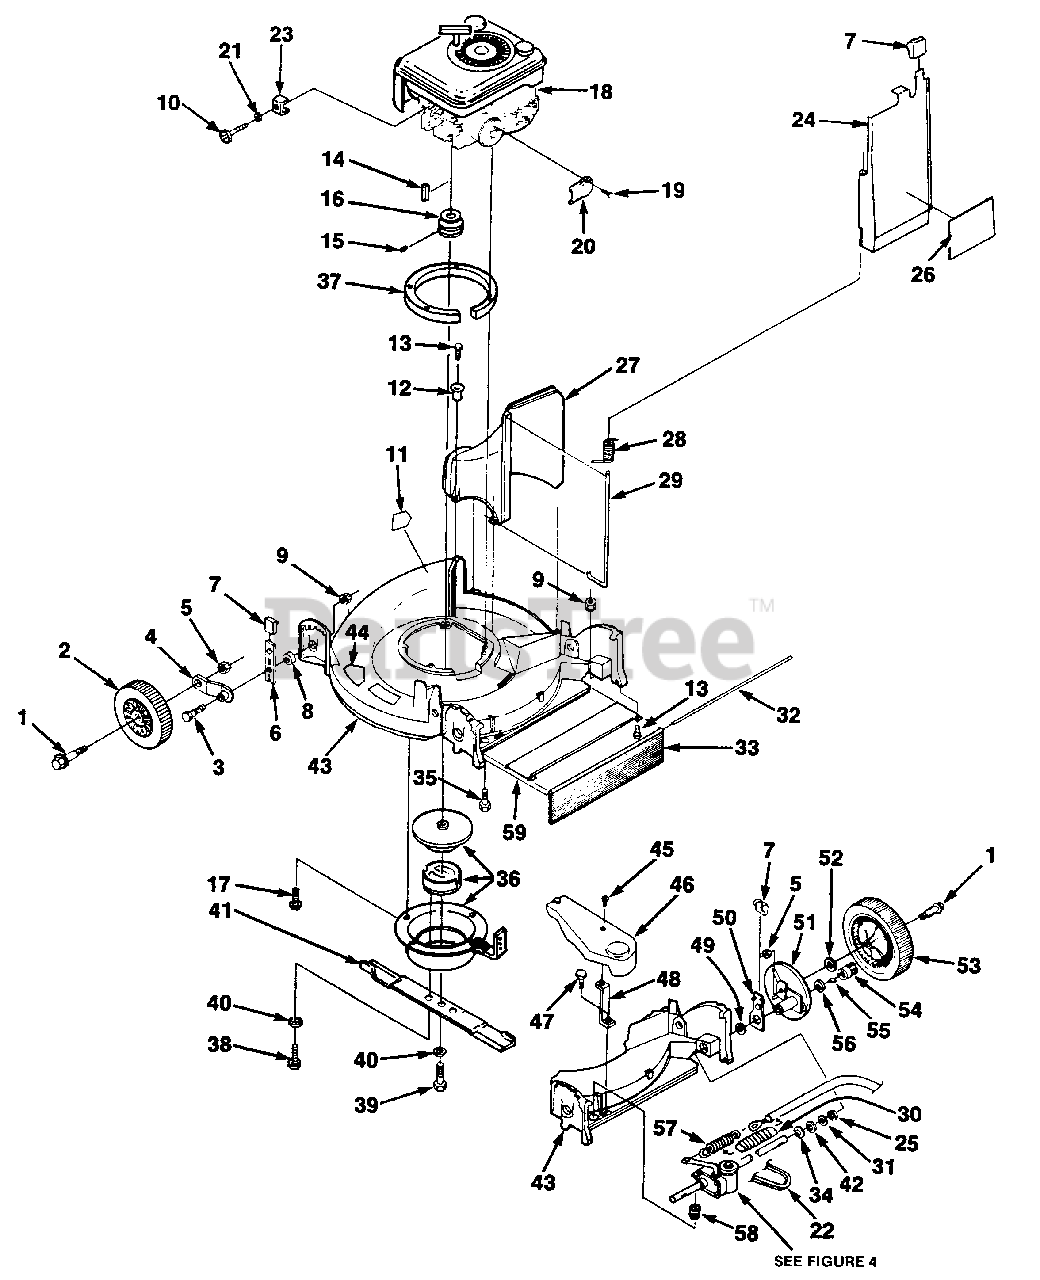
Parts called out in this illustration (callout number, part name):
1	BOLT- Axle
2	WHEEL & TIRE ASSY.
4	WHEEL- Adjuster arm
5	NUT- (3/8-16)
6	SPRING
7	KNOB
9	NUT- Flange (5/16-20)
10	SCREW- Hex hd. (1/4-20 x 1/2")
11	DECAL- Warning
13	SCREW- (1/4-20 x 3/4")
14	KEY- (5/8 x 5/32")
15	SCREW- Set (8/32")
16	PULLEY- Drive
17	SCREW- (5/16-18)
18	ENGINE- 4.0 H.P.
19	SCREW- (#8-32 x 3/8")
20	DEFLECTOR
21	WASHER- Lock (1/4")
22	BELT- Drive
24	DOOR- Chute
26	DECAL- Door
29	PIN- Hinge
30	COVER- Spring
32	ROD- Drag flap
33	FLAP- Drag
34	RING- Eaton
35	SCREW- (3/8-16 x 2 1/4")
36	BLADE/BRAKE/CLUTCH
37	RING- Engine
38	SCREW- (3/8-16 x 1")
39	SCREW- (3/8-24 x 2")
40	WASHER- Lock (3/8")
41	BLADE- (21")
43	DECK ASSY.
44	DECAL- Foot pad
45	SCREW- (1/4-20 x 3/4")
46	COVER- Drive
47	SCREW- Hex (#10-16)
51	DRIVE WHEEL SUPPORT ASSY.
53	WHEEL & TIRE
54	PINION (R.H.)
55	PAWL- Pinion
57	SPRING- Extension
58	SPRING- Compression
